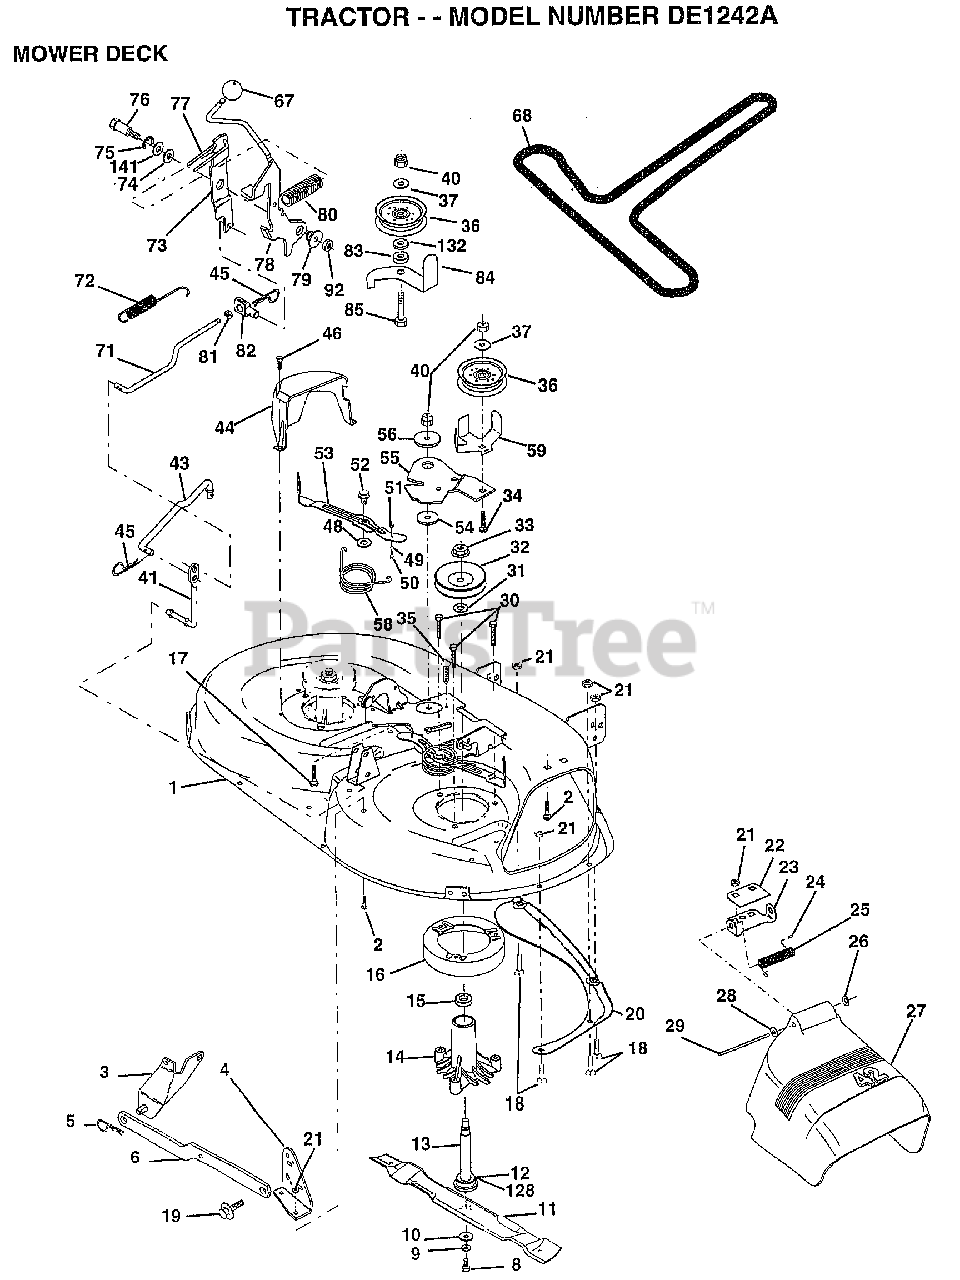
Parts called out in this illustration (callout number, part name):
1	"HOUSING ASSY.42"""
2	BOLT
3	BRKT ASM SWAY BAR
4	BRKT DECK SW BAR
8	BLADE BOLT
10	WASHER.HARD.BLADE
11	"BLADE.42"" HIPERF"
12	BEARING.BALL
14	HSG ASM MANDREL
15	BEARING
16	STRIPPER RND MWR
17	BOLT RDHD 3/8-16
18	BOLT
19	BOLT SHD 5/16-18
20	BAFFLE VORTEX 42
22	STIFFENER BRKT
23	DEFLECTOR BRKT
24	CAP-SLEEVE LT
25	SPRING TORSION
26	NUT PUSH M
27	DEFLECTOR.SHIELD
28	WASHER
29	HINGE ROD
30	"SCREW-THD ROLL,WA"
31	WASHER
32	PULLEY.MANDREL.42
34	BOLT
35	XMAS TREE FASTNER
36	FLAT IDLER PULLEY
37	WASHER
41	PIVOT ROD
43	ROD CLUTCH W/NIBS
44	GUARD MAND LH BLK
45	RETAINER M
46	SCREW.1/4-20X5/8
48	HARD SMALL WASHER
49	ROLLER ASM-CAM
50	SHOULDER BOLT
51	LOCKNUT
52	BOLT.SHLD.5/16-18
53	BRAKE PAD ARM ASM
54	HARDENED WASHER
55	ARM-IDLER
56	SPACER RETAINER
58	SPRING TORSN BRAK
59	GUARD IDLER TUV
67	KNOB.RD.7/16-14
68	BELT.V.T-PATH
71	ROD CLUTCH 38/42
72	RETURN SPRING
73	CLUTCH ARM SECOND
74	WASHER
75	RING
76	SHOULDER BOLT
77	SPRING KEEPER
78	LEVER.ASM.CLUTCH
79	BUSHING
80	SPRING.CLUTCH.MWR
81	NUT
82	TRUNION ADJ
83	WASHER
84	"KEEPER-BELT,FIXED"
85	BOLT
92	NUT
128	WASHER.FELT.
132	WASHER GT
141	WASHER .T
